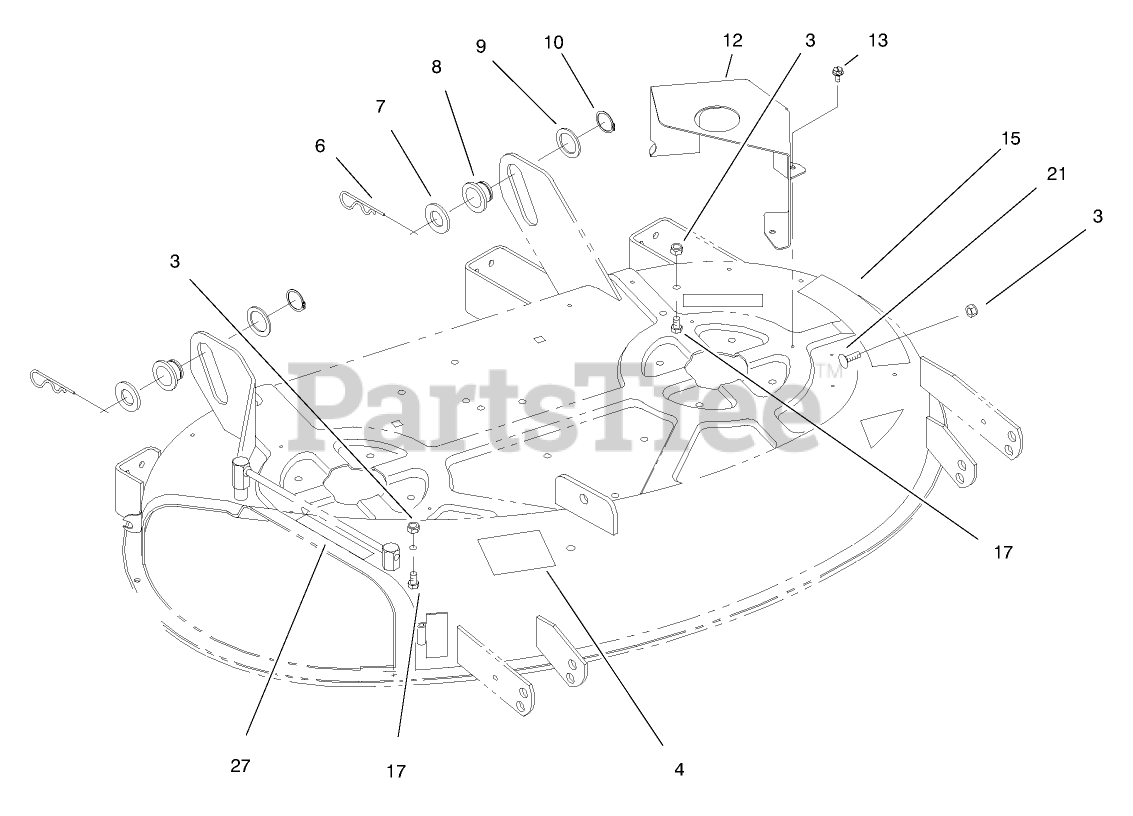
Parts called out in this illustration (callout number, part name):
3	NUT-LOCK, NI
6	PIN-HAIR
7	WASHER-FLAT
8	ROLLER-LIFT
9	WASHER-FLAT
10	RING-RETAINING
12	COVER-BELT
13	SCREW-HWHTF
15	DECAL - DANGER
17	SCREW-HH
21	SCREW-CARR
27	DECAL-DANGER
